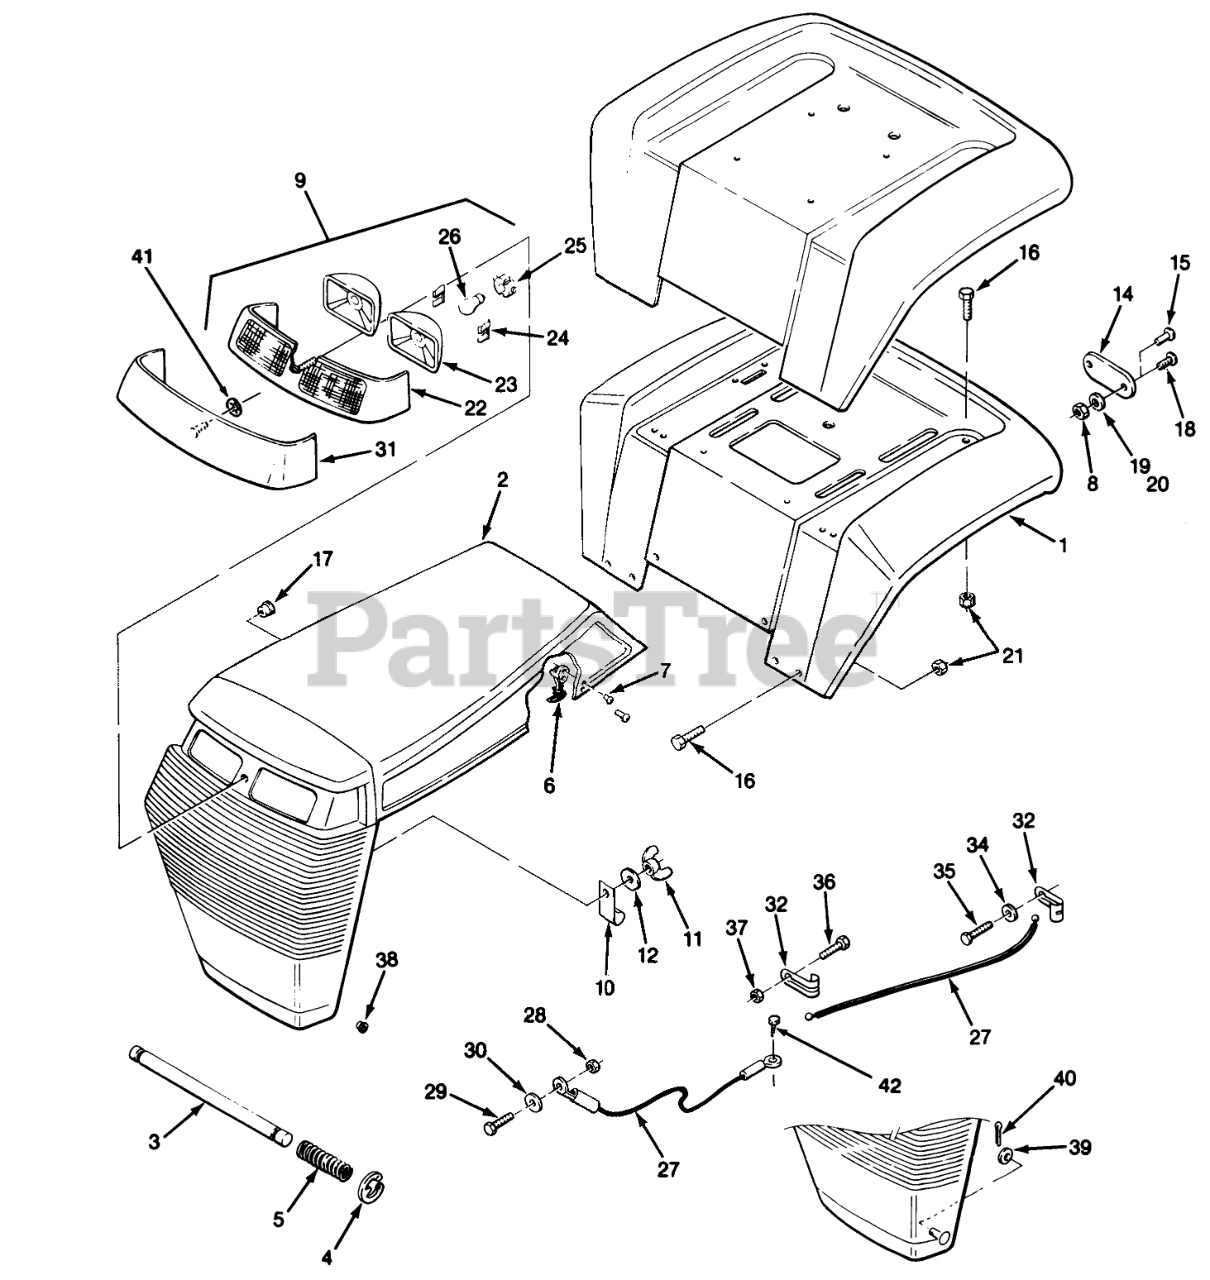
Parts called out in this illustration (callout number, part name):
1	FENDER R
2	Hood & Grill (210-5 & 210-H)
4	E-Ring
5	SPRING
6	HANDLE ASM
7	RIVET-POP
8	Nut
9	Headlight Bar Assembly (Incl. Ref. #22-24 & 26)(212-5 & 212-H)
10	J-CLIP
11	WING NUT
12	WASHER
14	Reflector
15	Poprivet
16	SCREW-CARR
17	BUSHING-NYLON 1.093
18	Screw
19	WASHER
20	Lockwasher
21	Nut
22	LIGHT-BAR BLACK
23	LIGHT POD
24	RETAINER
25	SOCKET-HEADLIGHT
26	BULB
27	CABLE-HOOD LANYARD
28	Nut
29	Screw-Machine
30	WASHER-BACKING
31	COVER-LIGHT OPENING
32	CLEVIS
34	Washer
35	Screw
36	Screw-Machine
37	Nut
38	NYLINER BUSHING
39	WASHER-PLAIN
40	PIN-COTTER
41	RING-RETAINING
42	Screw
